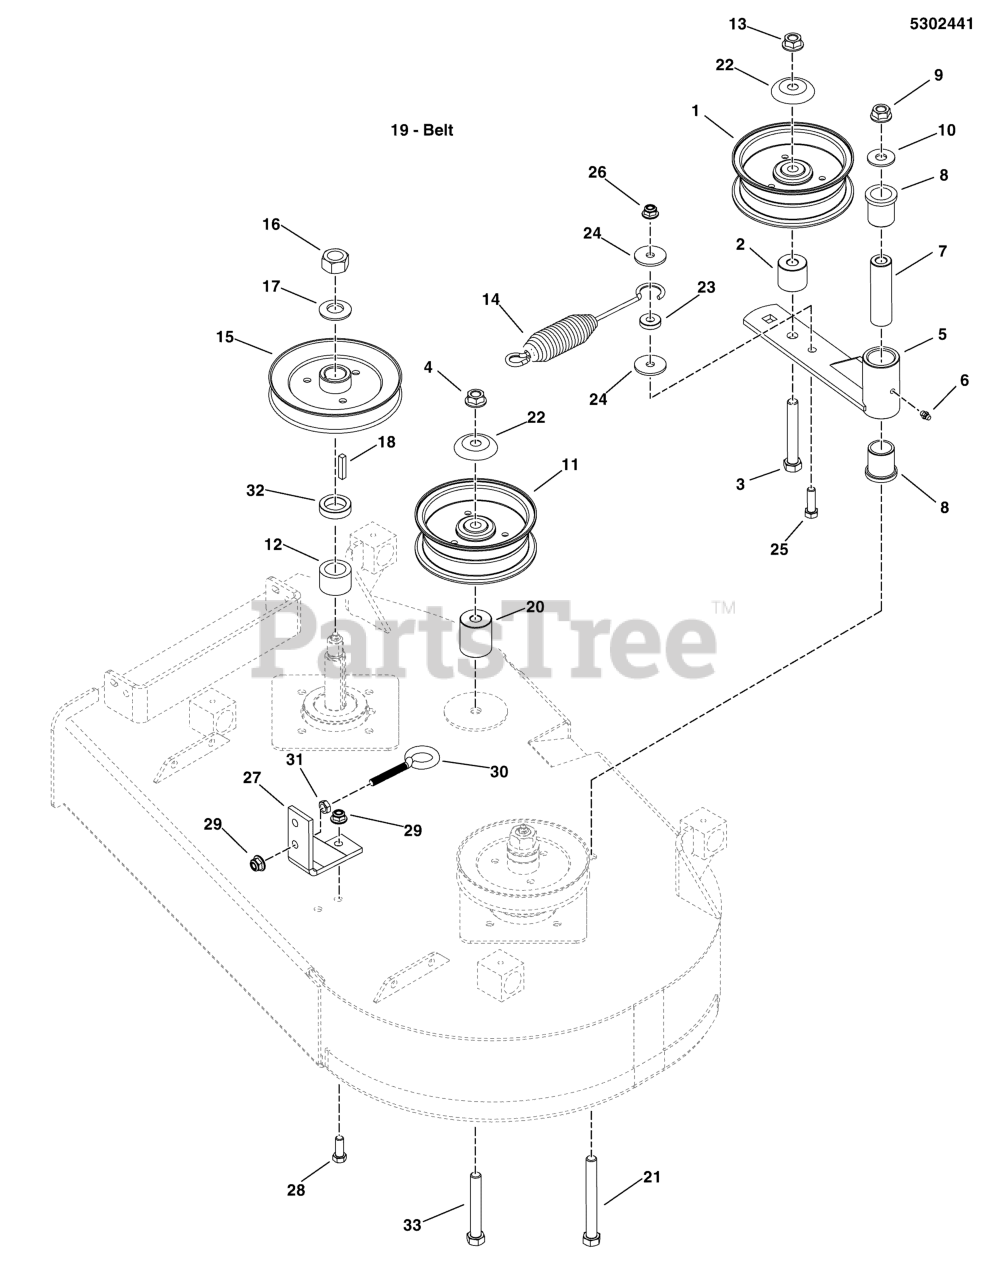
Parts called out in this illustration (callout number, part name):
1	PULLEY, IDLER, 5.00 WIDE W/ .51 BORE
2	SPACER, .52 X 1.38 X 1.25, CZ
3	BOLT, 1/2-13 X 3" GD5 CZ
4	NUT, Hex Flange, Nylock, 1/2-13
5	WELD, IDLER ARM SHORT - RED
6	GREASE FITTING, 1/4-28 STRAIGHT
7	SPACER, .52 X 1.00 X 3.50
8	BUSHING, FLANGE
9	NUT, 1/2-13 HEX NYLON LOCK
10	WASHER, 1/2 USS
11	PULLEY, IDLER, 5.00 WIDE W/ .51 BORE
12	SPACER, 1.00 X 1.50 X 1.00 CZ
13	NUT, Hex Flange, Nylock, 1/2-13
14	SPRING, EXTENSION, SWIVEL. LONG HOOK
15	PULLEY-6.122 OD X .98 BORE
16	NUT, 3/4-16 HEX
17	WASHER, 3/4 BELLEVILLE
18	KEY, 1/4 SQ X 1-1/4
19	BELT, BP-SEC, 87.99EL, ARAMID, WRPD
20	SPACER. .52 X 1.50 X 1.75, CZ
21	BOLT, 1/2-13 X 4-1/2 GD5 YZ
22	SHIELD, PULLEY BEARING
23	SPACER, .39 X 1.00 X .25
24	WASHER, .390 X 1.50 X .109, YZ
25	BOLT, 3/8-16 X 1-1/4" GD5 CZ
26	NUT, 3/8-16 HEX NYLOCK FLANGE
27	WELD, ANCHOR EYEBOLT - RED
28	BOLT, 3/8-16 X 1" GD5 CZ
29	NUT, 3/8-16 HEX NYLOCK FLANGE
30	EYE BOLT, 3/8-16 X 5, 2.88THRD, 1EYE, CZ
31	NUT, 3/8-16 HEX JAM
32	SPACER, 1.01 X 1.50 X .37, CZ
33	BOLT, 1/2-13 X 3-1/2, HEX HD, GD5, CZ (SV)
